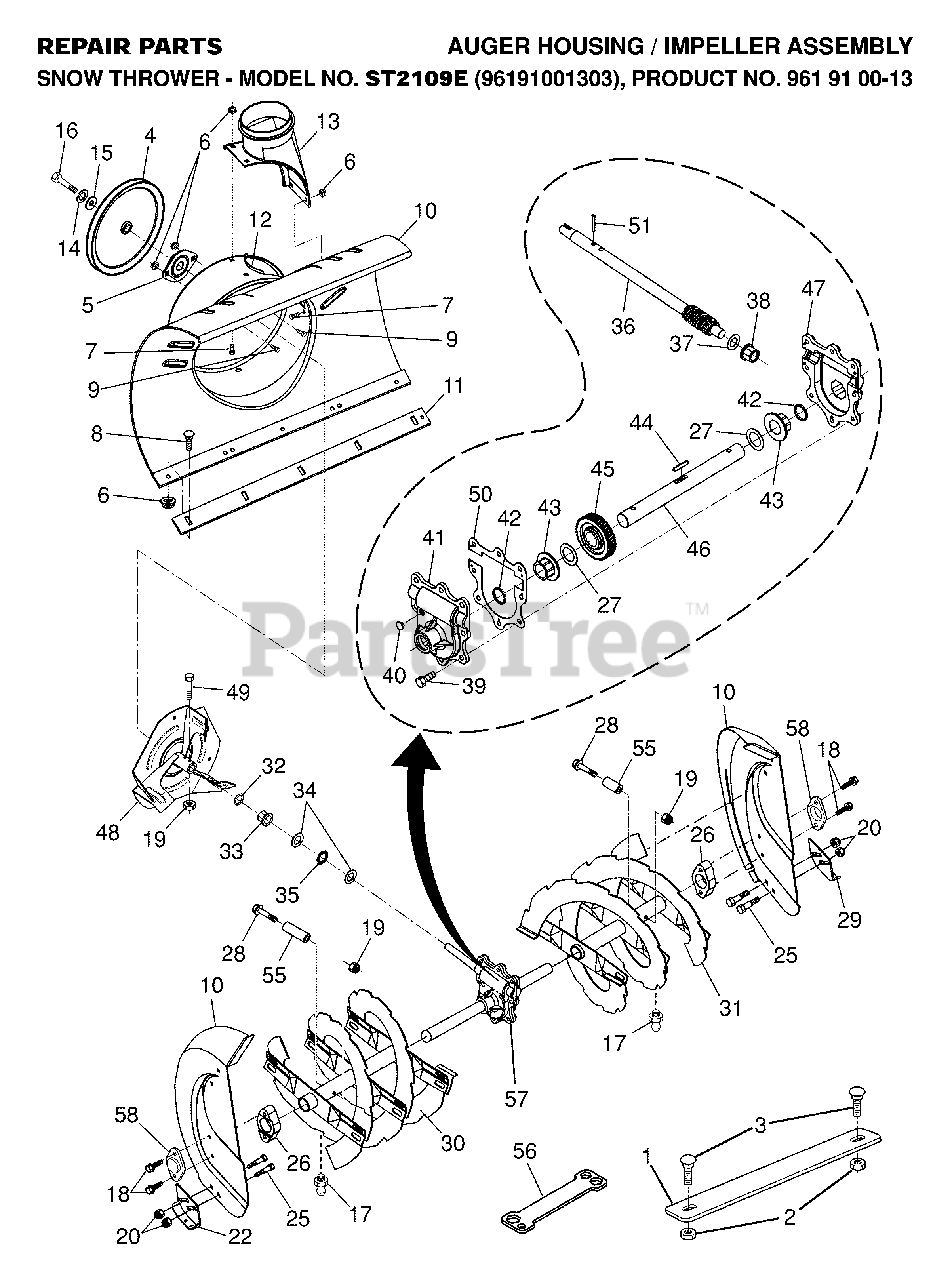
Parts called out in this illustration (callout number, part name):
1	WEIGHT, AUGER HOUSING 27
2	NUT, LOCK 5/16-18
3	BOLT.CARRIAGE.5/16-18
4	PULLEY, IMPELLER
5	BEARING FLANGE
6	NUT, HEX FLANGE 5/16-18
7	BOLT.CARRIAGE.5/16-18X
8	BOLT
11	BAR, SCRAPER
12	BRACKET, CORNER DISCHARGE
13	BASE DISCHARGE CHUTE
14	WASHER, FLAT
15	WASHER, LOCK 5/16
17	GREASE FITTING
18	SCREW, HEX HD 5/16X1
19	LOCKNUT
20	NUT, HEX FLANGE 5/16-18
22	SKID PLATE RH
26	BEARING.BALL.AUGER.SHAFT
27	WASHER TRUST 1"
28	BOLT, SHEAR
29	SKID PLATE LH
30	AUGER ASSY-RH
31	AUGER ASSY-LH
33	BUSHING, FLANGE 3/4
34	WASHER, THRUST 3/4
35	BEARING TRUST 3/4
36	SHAFT, IMPELLER
37	WASHER, THRUST 5/8
38	BUSHING FLANGE 5/8
39	SELF-TAPPING SCREW 5/16-18X3/4
41	HOUSING.GEARBOX.RH.SNOW
42	SEAL, OIL
43	BUSHING FLANGE 1"
44	KEY, SQUARE 1/4 X .875
45	WORM GEAR
46	SHAFT, AUGER
47	LH GEARBOX HOUSING
48	IMPELLER ASSY
49	SCREW.HEX.HD1/4-20X
50	GASKET.AUGER.GEARBOX
51	PIN, ROLL 3/16 X 1-1/8
56	RP WRENCH, SNOWTHROWER
58	BEARING RETAINER, PLASTIC
